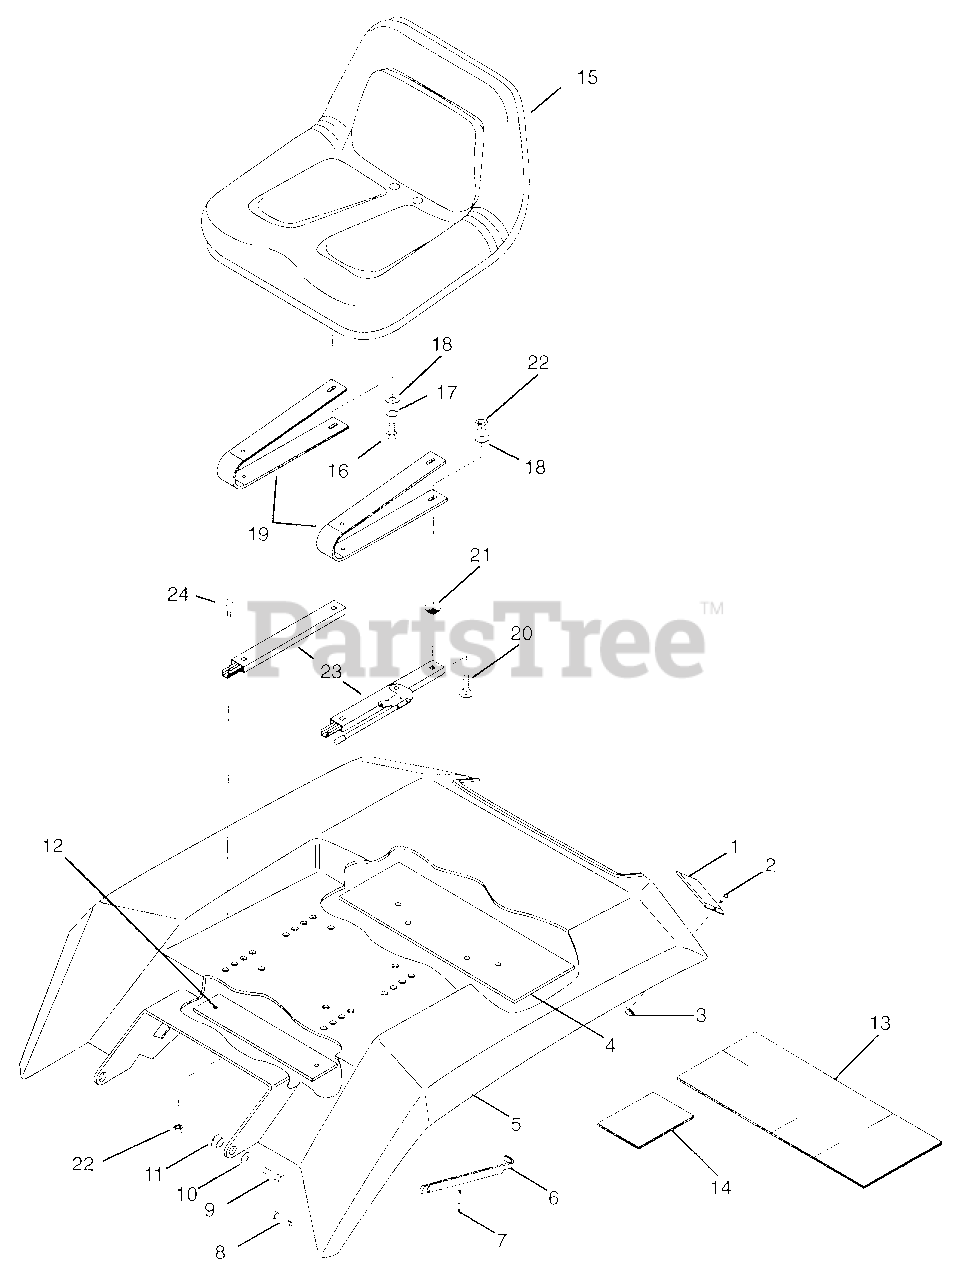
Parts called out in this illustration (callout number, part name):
1	Reflector-Rectangular Reflex
2	Screw-Machine 10-32 x .50
3	Nut-Locking 10-32
4	Bracket-Seat Support
5	Weldment-Seat Pan Head Notched
6	Strap-Fender Hold Up
7	Pin-Cotter .062 x .75
8	Pin-Clevis .250 x .406
9	Bolt-Hex .38-16 x 1.00 Grade 5
10	Washer-Flat-Steel .406 x .812 x .065
11	Bushing-Flange .406 x .88 x .270 x .140
12	Plate-Control Shaft
13	Heat Shield
14	Heat Shield
15	Seat V-560
16	Bolt-Hex .31-18 x .75
17	Washer-Lock .31 x .078
18	Washer-Flat-Steel .344 x .688 x .065
19	Seat Spring
20	Bolt-Round Head Square Neck .31-18 x 1.00 Grade 5
21	Seat Slide Spacer
22	Nut-Locking-Center .31-18
23	Seat Slides
24	Screw-Cap Button Head .31-18 x .75 Grade 5
25	Nut-Hex .31-18
